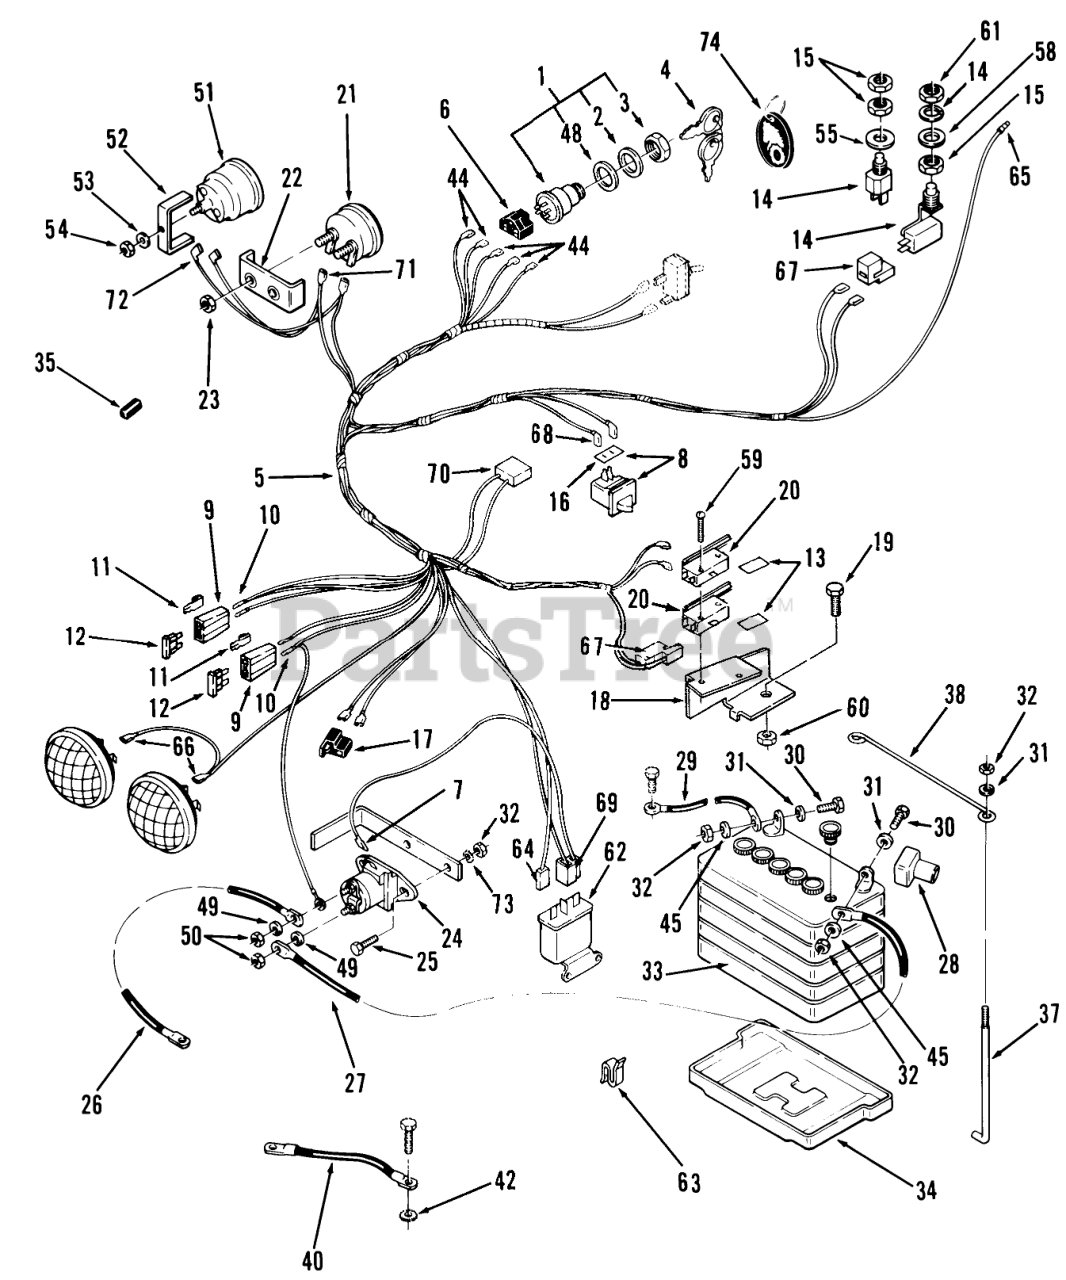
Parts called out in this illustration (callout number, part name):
1	Ignition Switch Ass-y
2	LOCKWASHER
4	KEY PADDED
4	Ignition Key
5	WIRING HARNESS
6	CONNECTOR-5 WAY-SERV
7	Terminal-Part of 5
8	SWITCH ASM (SERVICE)
9	AUTO-FUSEBLOCK TERM
10	TERMINAL FUSE
12	FUSE-BLADE, 5 AMP
13	BARRIER - SWITCH
14	Seat Switch 211-5, YT12A Only
14	SWITCH-SEAT
15	NUT-HEX, SPECIAL
16	SHIELD-DIRT SPST
17	CONNECTOR BODY
18	Support-Switch
19	Bolt
20	SWITCH
21	Voltmeter (w/109650)
22	CLAMP MOUNTING
23	HEX NUT 10-32 E.S.
24	SOLENOID-STARTER
25	Screw
26	ASSY WIRE
27	CABLE-BLACK
28	Boot
29	ASSY WIRE
30	Bolt
32	Nut
33	Battery Maintenance Free 416
34	TRAY BATTERY
35	GRIP
38	ROD-HOLD DOWN
40	WIRE GROUND
42	Washer-Lock
44	Terminal
45	Washer
48	Washer
49	Washer
50	Nut
51	Hourmeter 314, 417
52	HOUR METER CLAMP
53	Lockwasher
54	Hex Nut
55	WASHER
58	SPACER SWITCH
59	Screw
60	NUT HEX 4-40 ELAST
61	NUT HEX SPECIAL
62	Relay
63	CLIP-CABLE
64	TERMINAL 10
65	Sur-Plug
66	Spade Terminal
67	CONNECTOR BODY
68	Terminal
69	CONNECTOR BODY B
70	HOUSING 3TERMINAL
70	Connector 416
71	TERMINAL-TAB RCPT
72	Terminal Part of 5
73	LOCKWASHER
74	Wheel Horse Logo Key Tag w/ Slit Ring 420 Only
